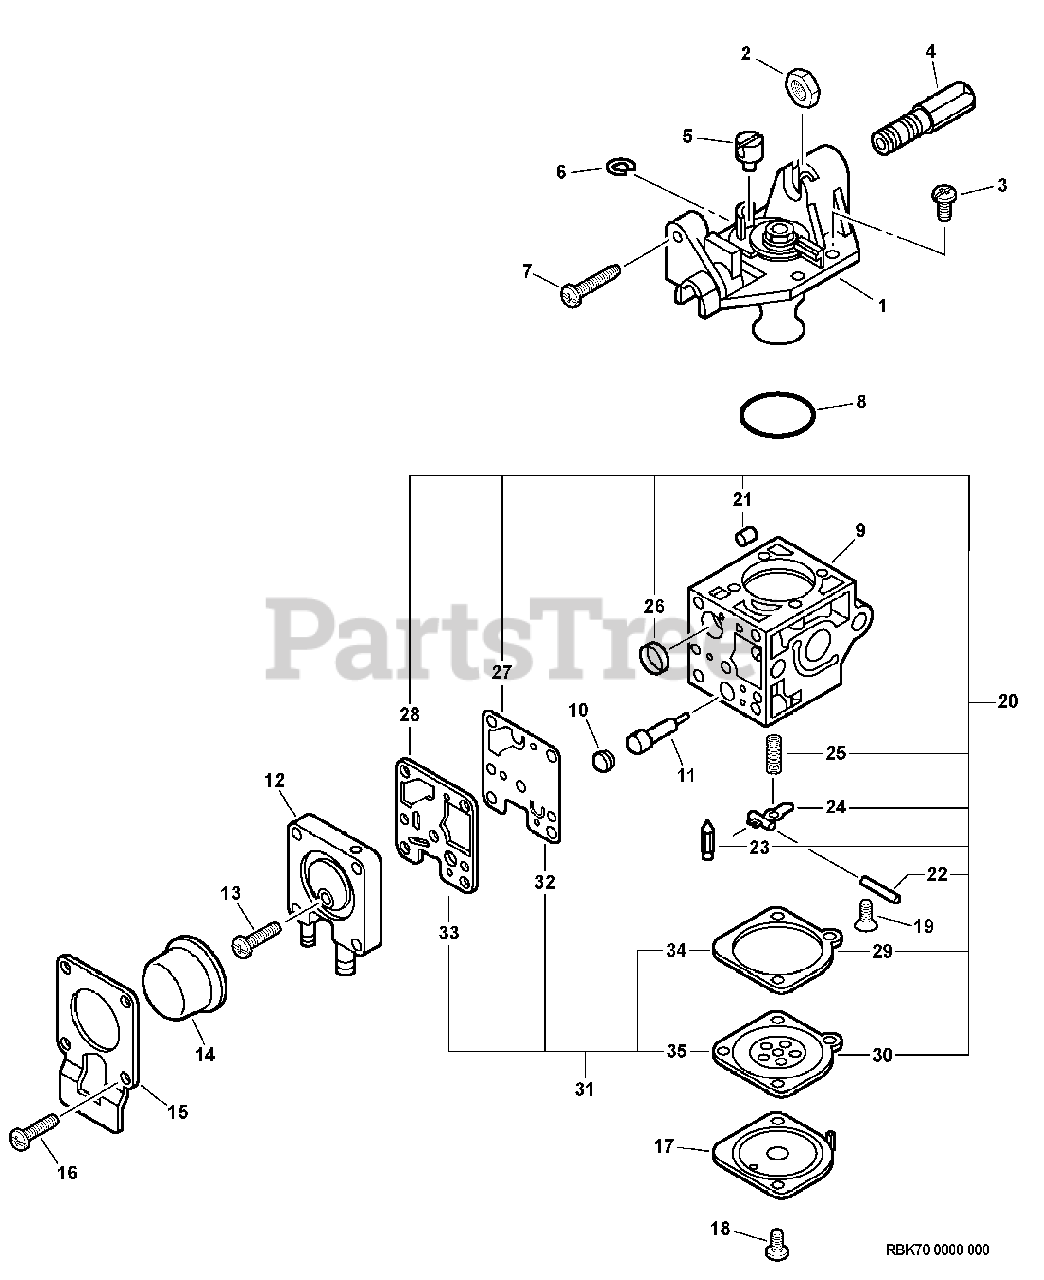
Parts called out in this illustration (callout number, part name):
1	ROTOR COVER ASSY
4	NUT, CABLE ADJUST
6	RING, RETAINING
7	SCREW, IDLE ADJUST
9	BODY, CARBURETOR
11	NEEDLE - HIGH SPEED
12	BASE, PURGE
13	SCREW, PURGE BASE
14	BULB, PURGE
15	RETAINER, PURGE BULB
16	SCREW, RETAINER
17	COVER, METERING
19	SCREW, METERING LEVER PIN
20	REPAIR KIT
21	GUIDE, ROLLER
22	PIN, METERING LEVER
23	VALVE, INLET NEEDLE
24	LEVER, METERING
25	SPRING
26	STRAINER
27	DIAPHRAGM, PUMP
28	GASKET, PUMP
29	GASKET, DIAPHRAGM
30	DIAPHRAGM, METERING
31	DIAPHRAGM/GASKET KIT
32	DIAPHRAGM, PUMP
33	GASKET, PUMP
34	GASKET, DIAPHRAGM
35	DIAPHRAGM, METERING
